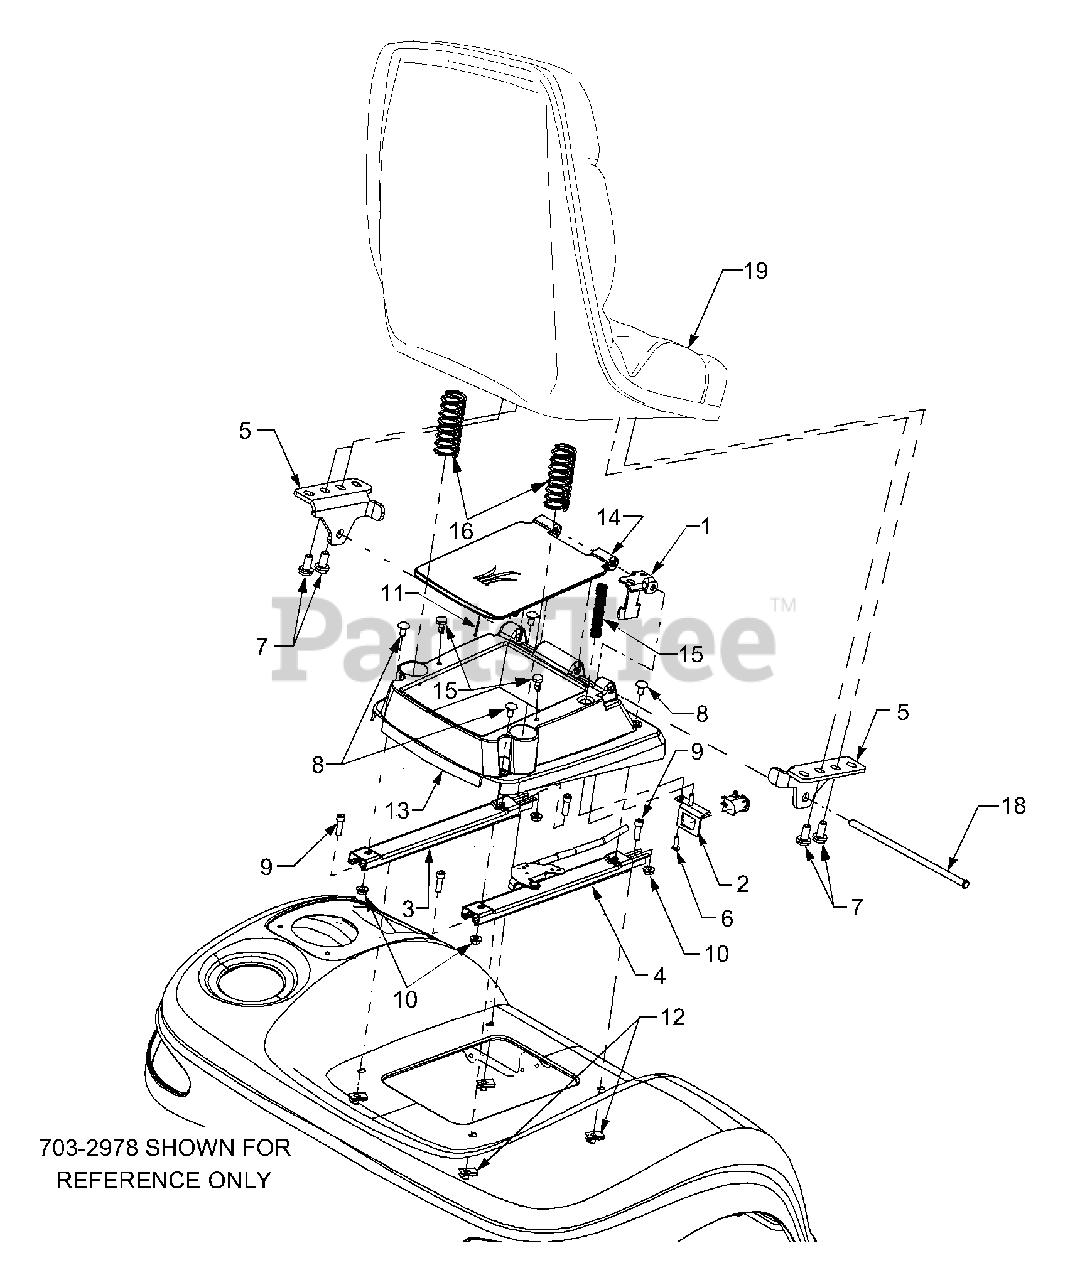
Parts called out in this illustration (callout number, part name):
1	Bracket, Seat Switch
2	Bracket, Switch Mounting
3	Track, Seat, w/o Latch
4	Track, Seat, w/Latch
7	Screw, Hex Wash. Hd 5/16-18 x .625
8	Carriage Bolt, 5/16-18 x .62
9	Screw, Pan Torx Hd 5/16-18 x 1.0
10	Nut, Hex Flange Lock, 5/16-18
11	Pin, Cotter, 3/32 x .75
12	Speed Nut, U-Type, 5/16-18
13	Base, Seat
14	Lid, Tlbx
15	Spring, Compression
16	Spring, Compression
18	Rod, Seat Pivot
19	Seat, High Back
